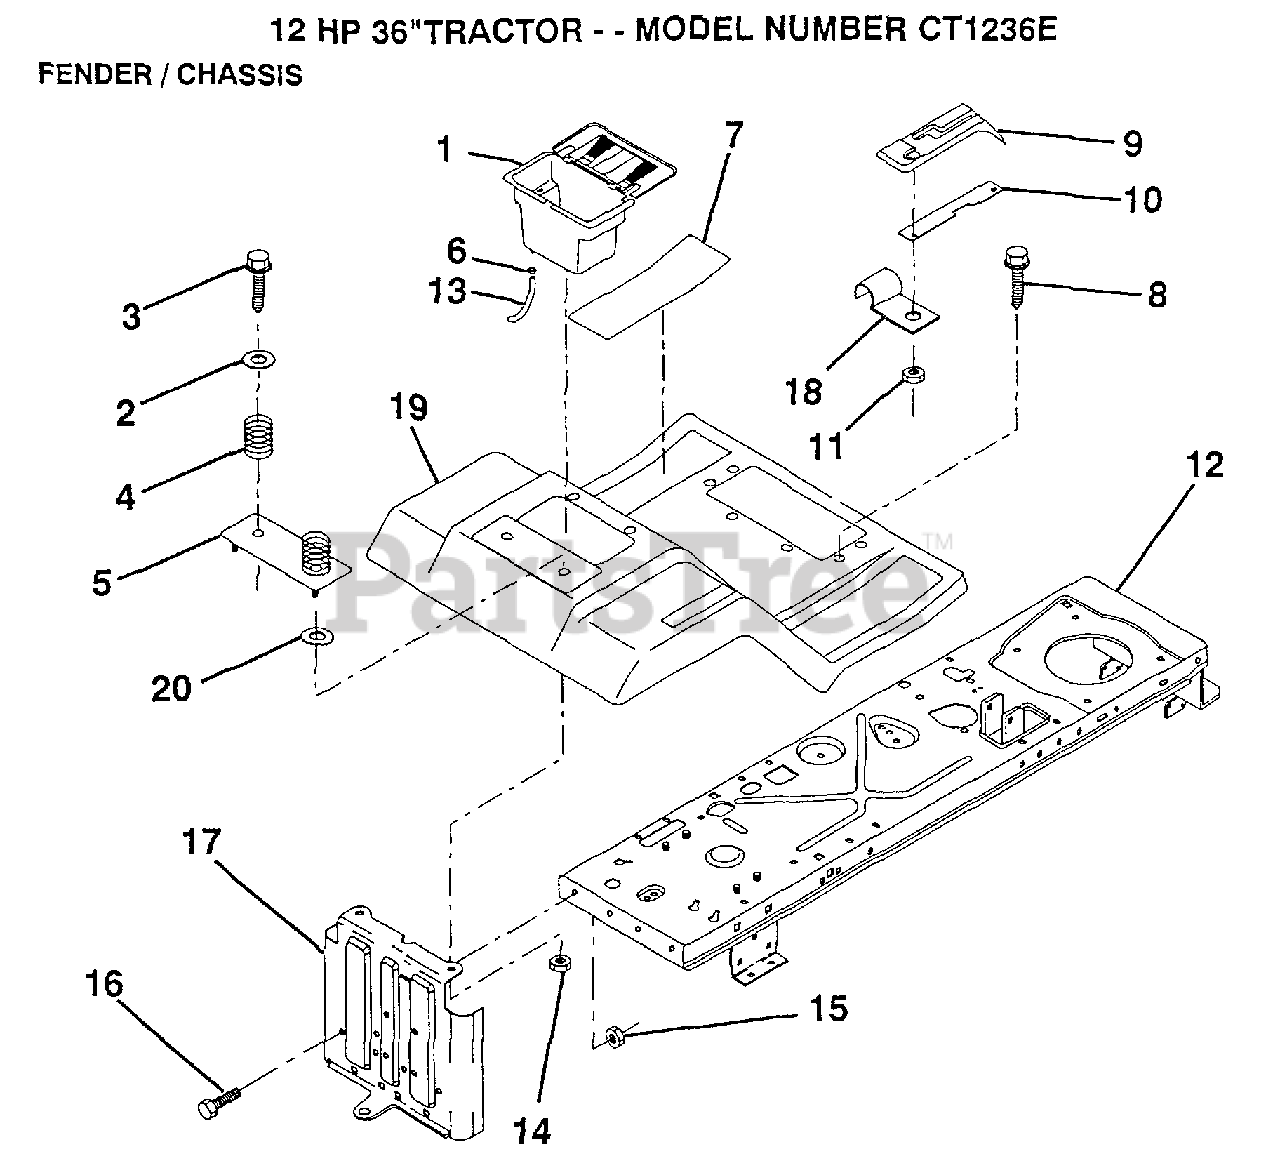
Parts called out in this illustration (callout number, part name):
2	WASHER
3	SCREW
4	SPRING COMPRESSIO
5	"PLATE, BATTERY"
6	HOSE CLAMP T
7	PAD FOOTREST
8	SCREW
10	"SHIFT LOCK, BAR"
11	NUT
14	NUT
16	BOLT
17	DRAWBAR
18	"CLIP,INSULATOR"
